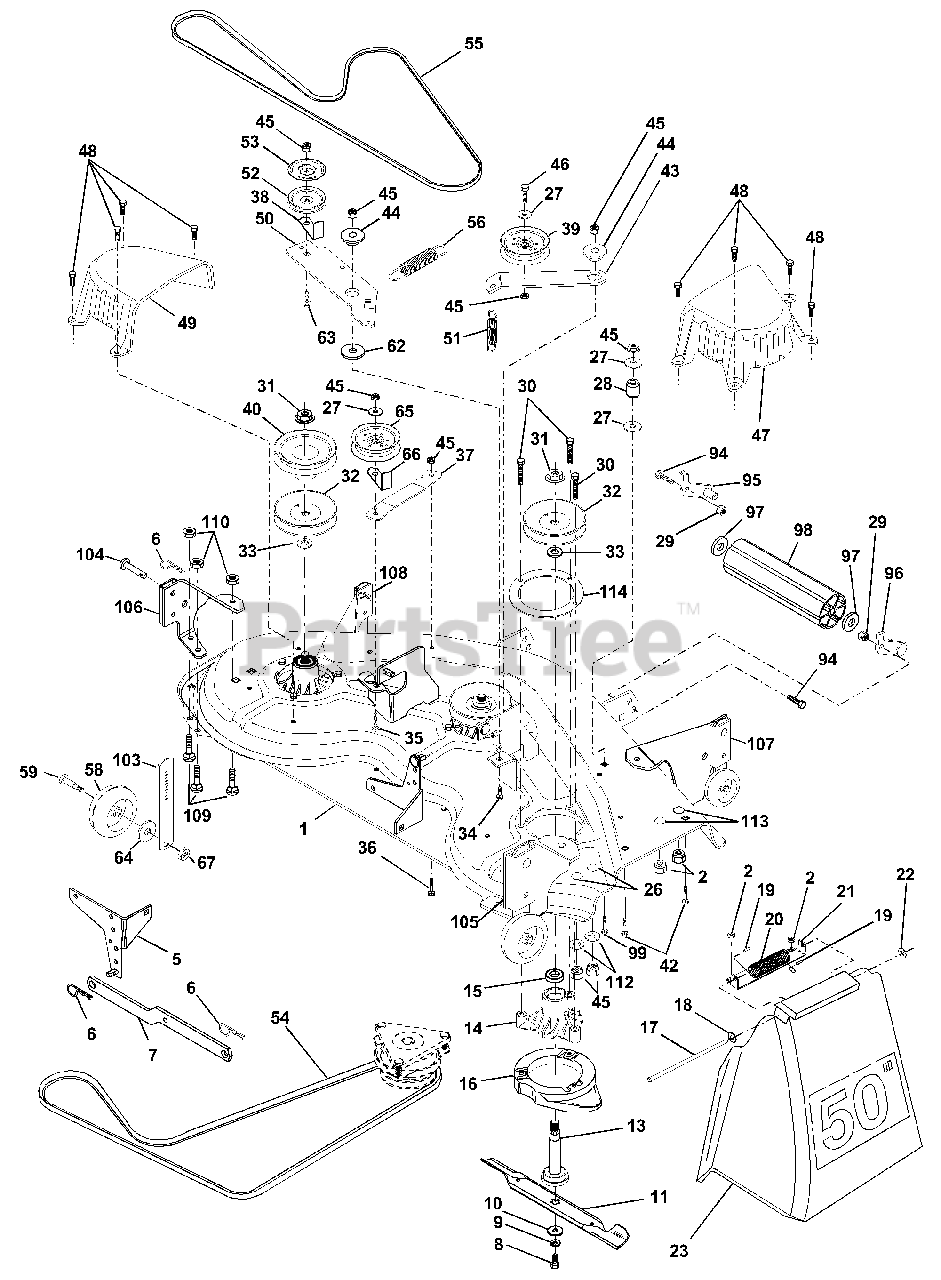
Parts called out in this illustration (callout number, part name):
1	Deck Asm., Mower 50"
2	Nut, Crownlock 5/16-18
5	Bracket Asm., Sway Bar
6	Retainer, Spring
7	Arm Suspension, Rear
8	Bolt 3/8-24 x 1.25 Gr. 8 Patched
9	Washer, Lock Hvy 3/8 Unplated
10	Washer, Hard Blade Mower Vented
11	Blade
13	Shaft Asm., W/Lower Brg
14	Housing, Mandrel 50" Vent
15	Bearing, Ball Mandrel
16	Stripper, Mower Vented
17	Rod, Hinge
18	Washer 11/32 x 5/8 x 16 Ga.
19	Cap Sleeve
20	Spring, Torison Delector
21	Bracket, Deflector
23	Shield, Deflector Mower
26	Bolt Rd Hd Sht Sqnk
27	Washer 13/32 x 13/16 x 16 Ga.
28	Spacer, Spring Stop Idler
29	Nut, Lock 5/16-18
30	Screw Thd Rolling Washer Head
31	Nut, Flg Top Lock Cntr 9/16
32	Pulley, Mandrel, Plated
33	Washer, Spacer Mower Vented
34	Bolt, Carriage 3/8-16 x 1-1/4
35	Bolt, Carriage 3/8-16 x 2
36	Bolt, Carriage 3/8-16 x 1 Gr. 5
37	Stiffener, Arm Idler
38	Keeper, Belt Idler
39	Pulley, Idler Flat
40	Pulley, Driven, Plated
42	Bolt, Carriage 5/16-18 Unc x 3/4
43	Arm, Idler Secondary
44	Spacer, Retainer
45	Nut, Crownlock 3/8-16 Unc
46	Bolt, Fin Hex 3/8-16 Unc x 1-3/4
47	Cover, Mandrel RH
48	Screw, Thd Roll 1/4-20 x 5/8
49	Cover, Mandrel LH
50	Arm, Idler Primary
51	Spring, Secondary
52	Pulley, Idler V Groove
53	Shield, Idler
54	V-Belt, Mower Primary
55	V-Belt, Mower Secondary
56	Spring, Primary
58	Wheel, Gauge
59	Bolt, Shoulder
62	Washer Hardened
63	Bolt Carriage 3/8-16 x 1-1/2
64	Washer 3/8 x 7/8 x 14 Ga.
65	Pulley Idler Flat Mower
66	Keeper, Belt Idler Plated
67	Nut, Center Lock 3/8-16
94	Bolt H 5/16-18 x 1
95	Bracket, Asm. Noseroller LH
96	Bracket, Asm. Noseroller RH
97	Washer 17/32 x 7/8 x 16 Ga.
98	Roller, Nose
99	Bolt, Carriage 3/8-16 x 1-3/4 Gr. 5
103	Bar Adj. Gauge Wh.
104	Pin Head Rivot
105	Bracket Ga Wh Asm RH 50
106	Bracket Ga Wh Asm LH 50
107	Bracket Ga Wh Assy F RH 50
108	Bracket Ga Wh Assy F LH 50
109	Bolt Carriage 5/16- 18 x 5/8
110	Nut Crownlock 5/16-18
112	Washer 17/32 x 3/4 x 16 Ga.
113	Bolt Carriage 5/16-Unc 1/2
114	Reinforcement Mandrel Ring
